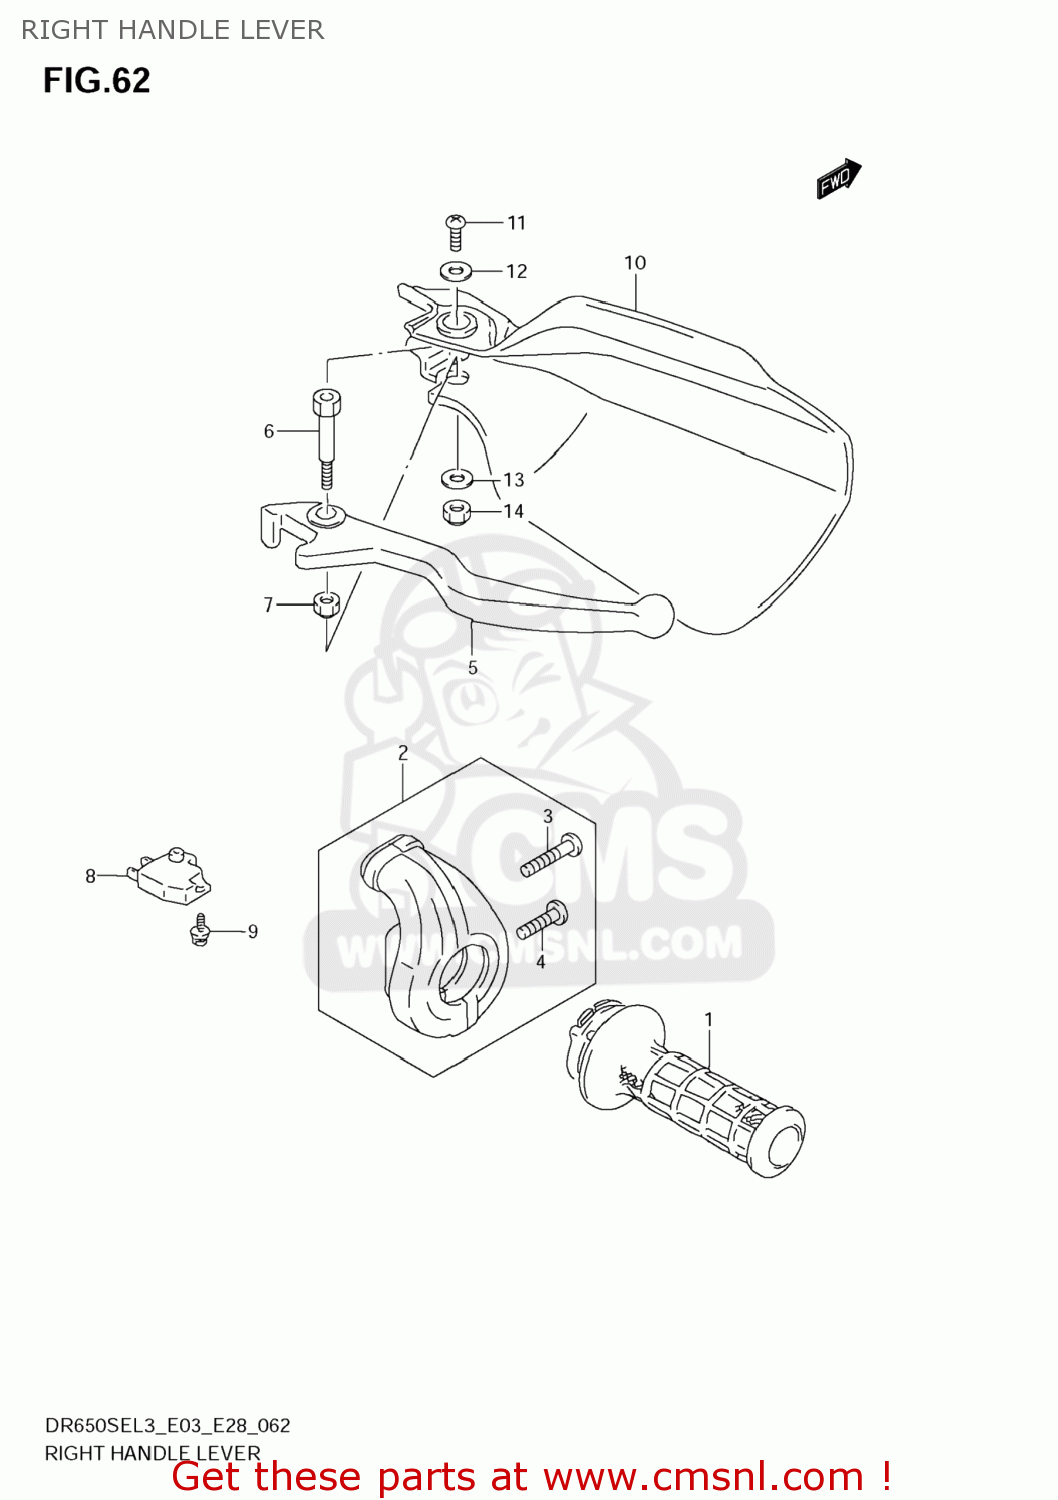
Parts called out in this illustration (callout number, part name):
1	GRIP,THROTTLE
2	CASE ASSY,THROTTLE
3	SCREW
4	SCREW
5	LEVER,BRAKE
6	BOLT,BRAKE LEVER PIVOT
7	NUT,LEVER PIVOT
8	SWITCH ASSY,FR BRAKE
9	SCREW
10	COVER,KNUCKLE,R
11	SCREW
12	WASHER(5.5X16X1.2)
13	WASHER(6.5X16X1.6)
14	NUT
